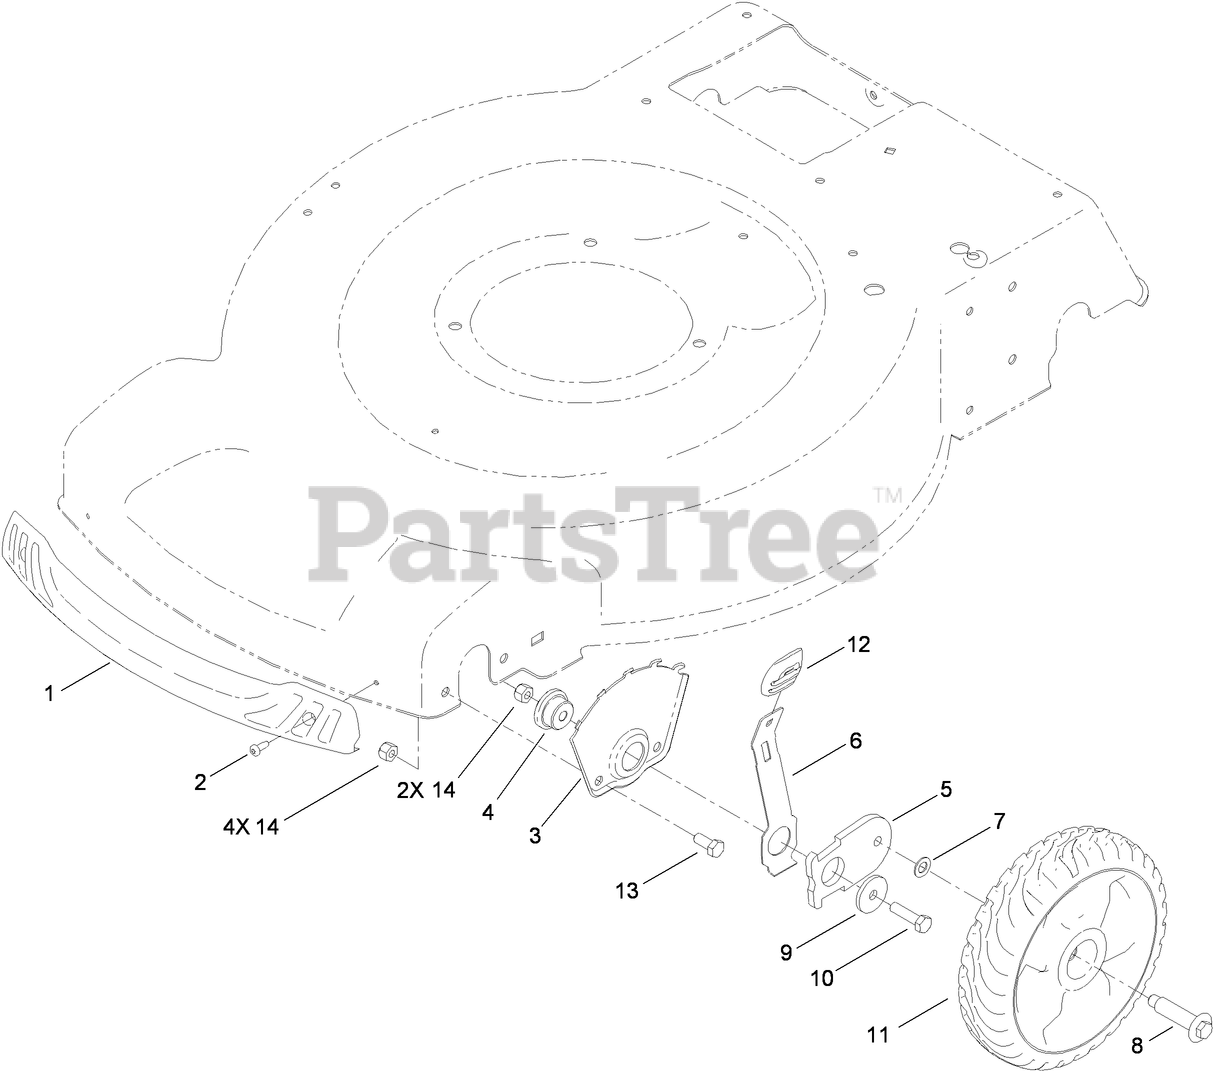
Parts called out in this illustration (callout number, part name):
1	BUMPER
2	SCREW-FORMING, THREAD
3	PLATE-HOC, FRONT
4	BUSHING-MOUNT, HOC
6	ARM-SPRING
7	WASHER
8	BOLT-SHOULDER
9	WASHER-FLAT
10	SCREW-HH
12	KNOB-LEVER, HOC
13	SCREW-HH
14	NUT-LOCK, NI
